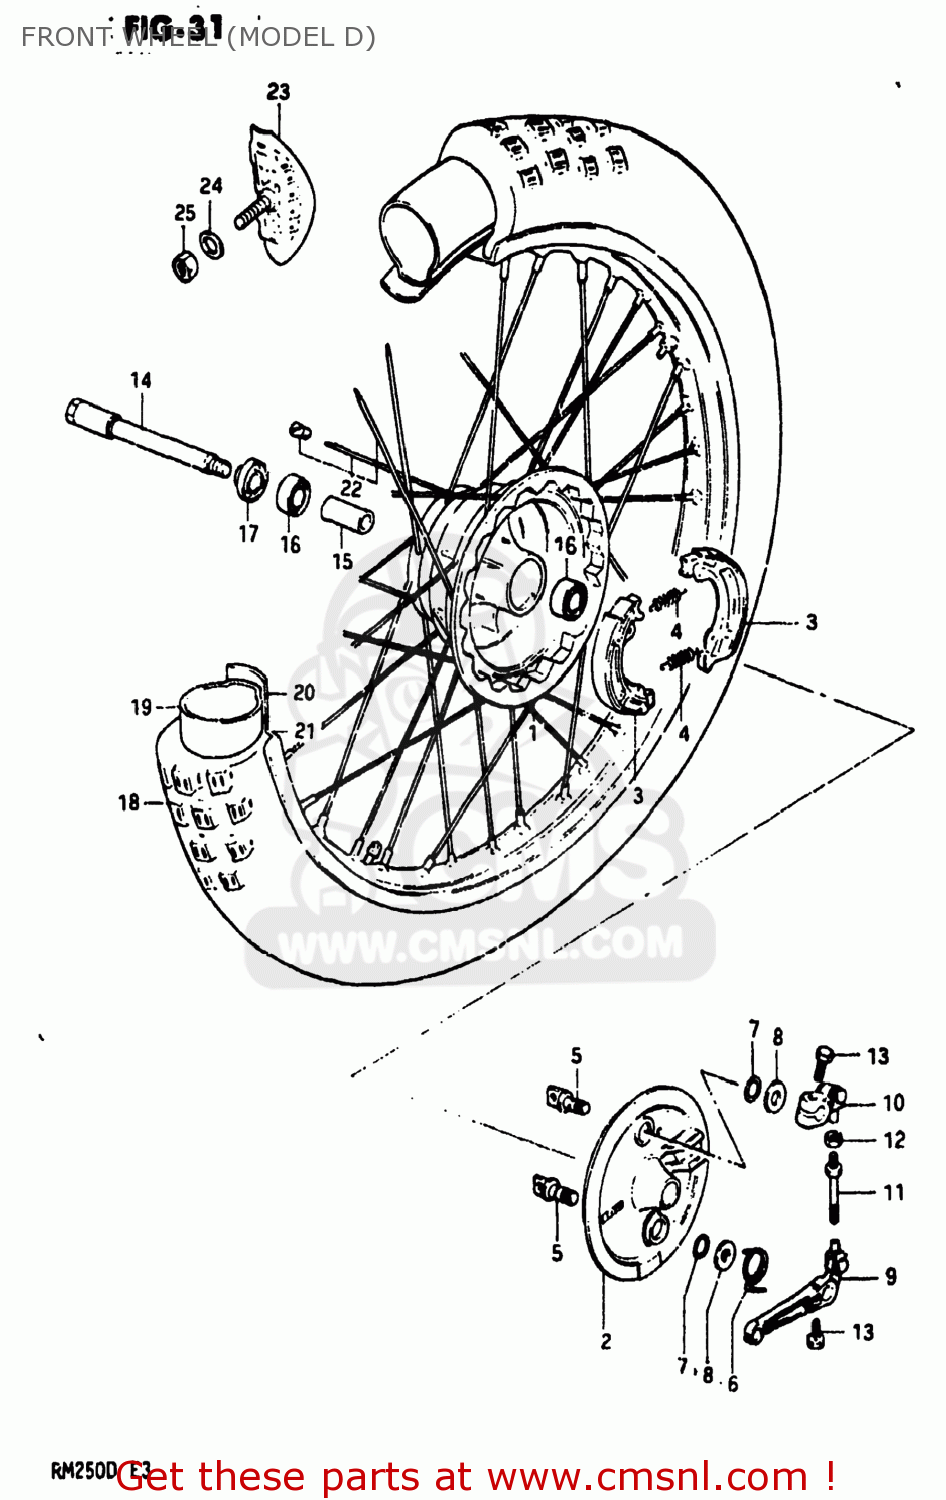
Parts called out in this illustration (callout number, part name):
1	HUB,FRONT
2	PANEL,FRONT HUB
3	SHOE,BRAKE (MCA)
4	SPRING
5	CAM,FRONT BRAKE
6	SPRING
7	O-RING (D:2 ID13.8)
8	WASHER (14.2X22X1)
9	LEVER, BRAKE CAM
10	LEVER ASSY, BRAKE CAM, NO.2
11	ROD,BRAKE CAM LEVER CONNECTION
12	NUT 6MM
13	BOLT
14	AXLE,FRONT
15	SPACER,FRONT HUB BEARING
16	BEARING
17	SPACER,FRONT AXLE,RIGHT
18	TIRE,FRONT
19	TUBE
20	PROTECTOR,WHEEL,INNER
21	RIM,FRONT WHEEL
22	SPOKE SET,FRONT
23	STOPPER,BEAD
24	WASHER
25	NUT 8MM
